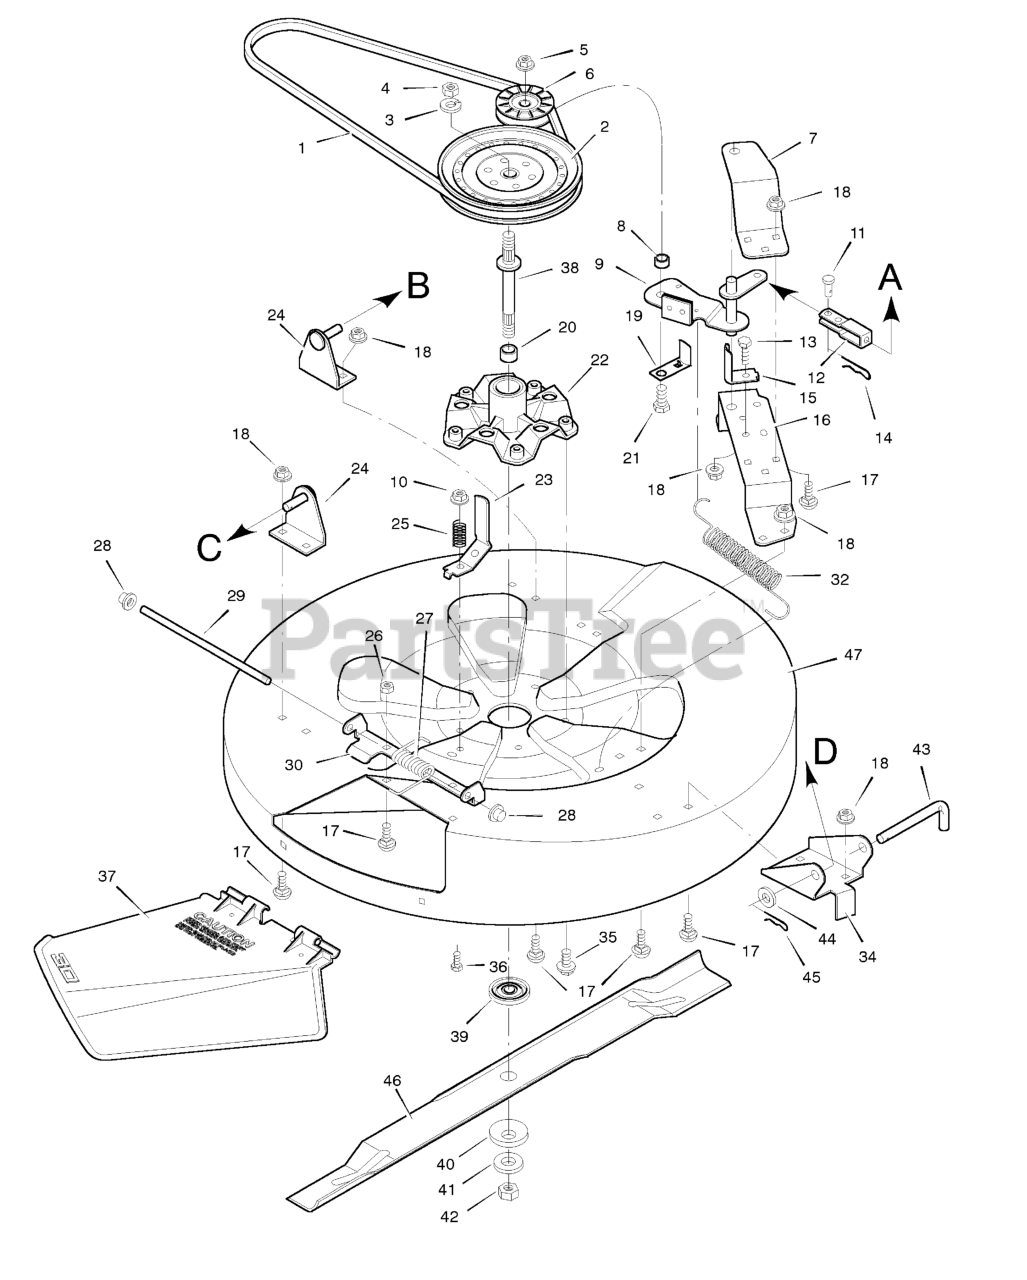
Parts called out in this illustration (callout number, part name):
1	Belt, Mower Drive
2	Pulley, Splined
3	Lockwasher
4	Locknut, Hex
5	Nut, Hex
6	Pulley, Idler
7	Bracket, Upper Idler
9	Assembly, Blade Idler
10	Locknut, Flange
11	Pin, Clevis
13	Bolt, Hex
14	Pin, Hair
15	Guide, Belt
16	Bracket, Lower Idler
17	Bolt, Carriage
18	Nut, Flange
19	Guide, Belt
21	Bolt, Hex
22	Housing, Mandrel
23	Guide, Belt
24	Bracket, Hanger
25	Spring, Compression
26	Nut, Hex
27	Spring - Torsional
28	Push On Cap
30	Hinge, Chute Deflector
32	Spring, Extension
34	Bracket, Front
36	Bolt, Hex
37	Deflector, Chute
38	Mandrel
39	Adapter, Blade
40	Washer, Belleville
41	Washer, Hardened
42	Nut, Hex
43	Pin, Pull
45	Pin, Hair
46	Blade, Standard
